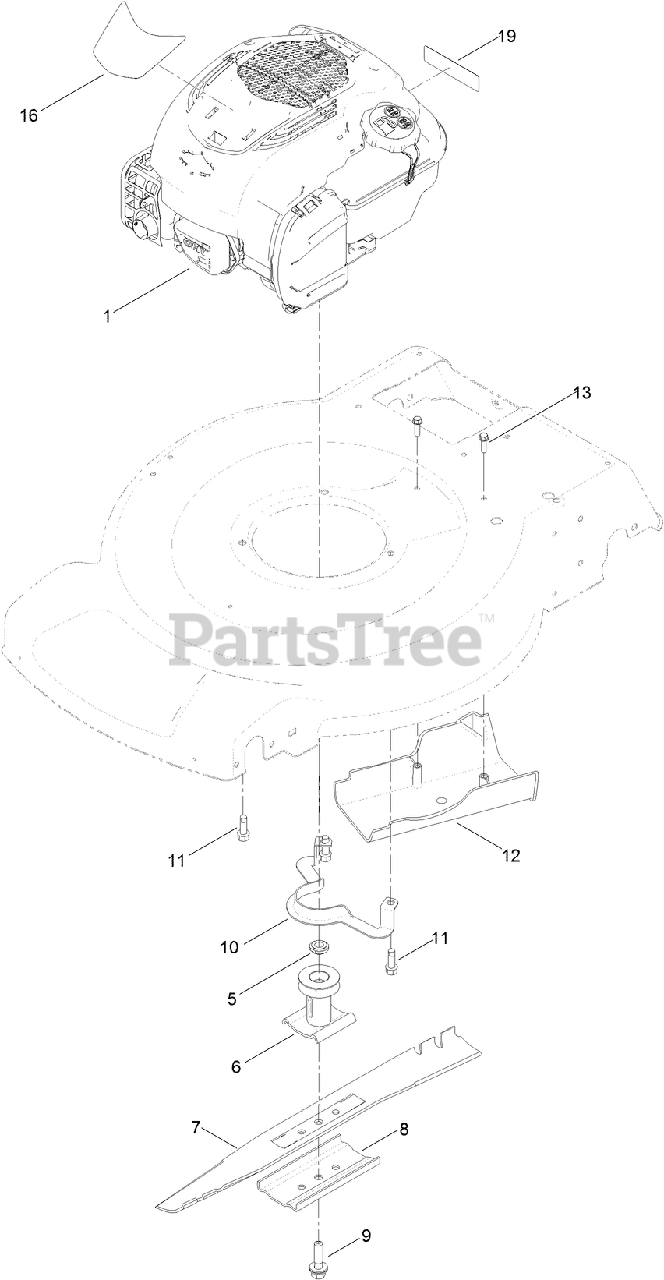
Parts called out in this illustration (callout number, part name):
5	SPACER-DRIVER
6	DRIVER-BLADE
7	BLADE-22 INCH
8	SUPPORT-BLADE
9	BOLT-BLADE
10	GUIDE-BELT
11	SCREW-TAPTITE
12	COVER-BELT
13	SCREW-HWH
16	DECAL-SHROUD
19	DECAL-ARRESTER, SPARK
